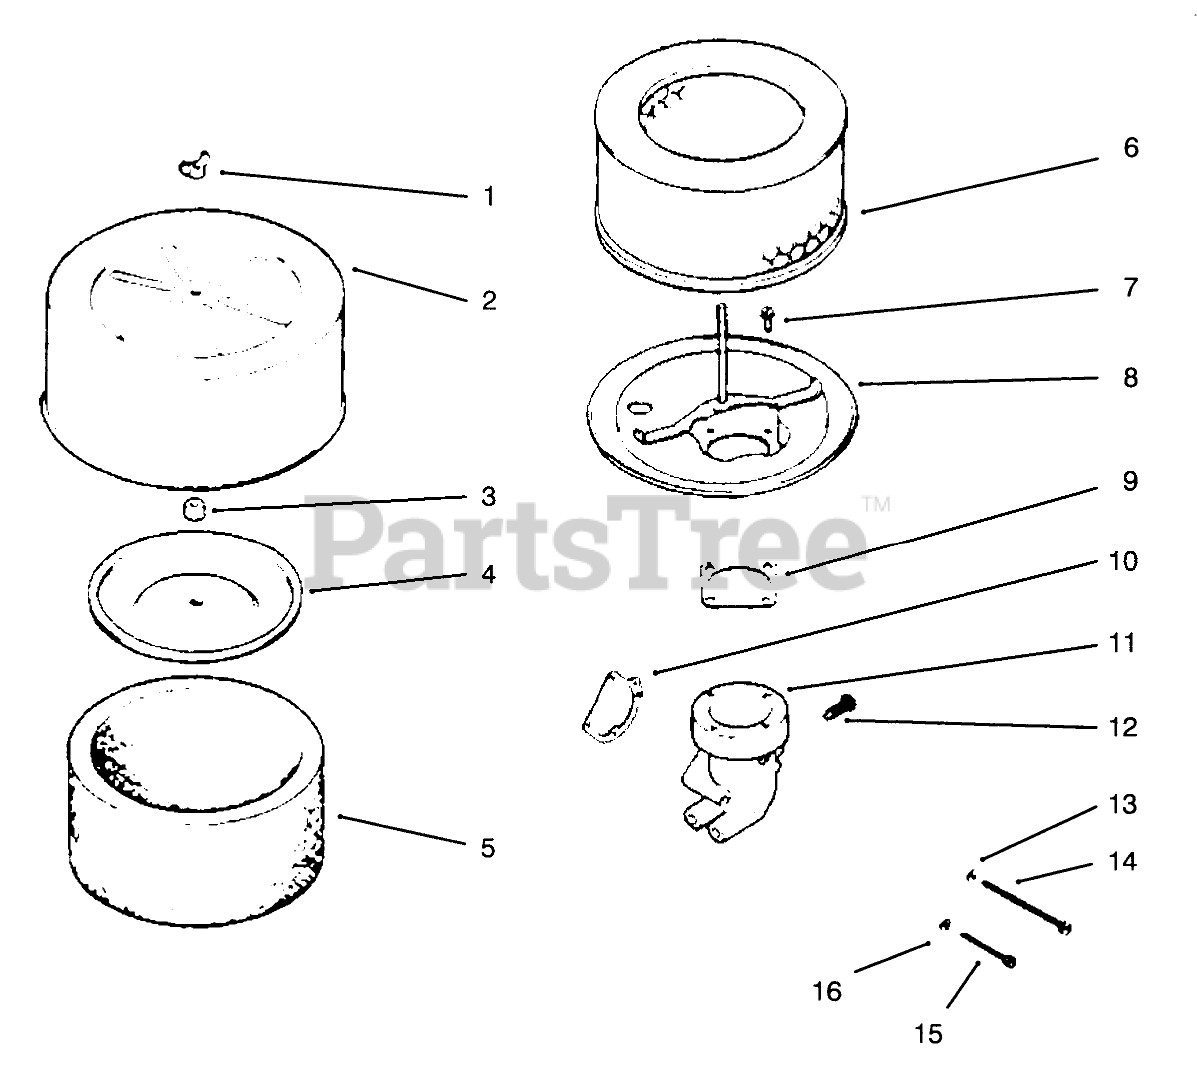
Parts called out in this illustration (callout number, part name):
1	Nut-Wing
2	Cover-Air Cleaner
3	Seal
4	Cover-Inner
5	Precleaner
6	Element
7	Screw-H.C.
8	Base-Air Cleaner
9	Gasket-Air Cleaner
10	Gasket
11	Elbow-Kit (Incl.Ref.#10 & 12)
12	Screw-Self Tap
13	Washer-Flat
14	Screw-R.H.M.
15	Screw-R.H.M.
16	Washer
